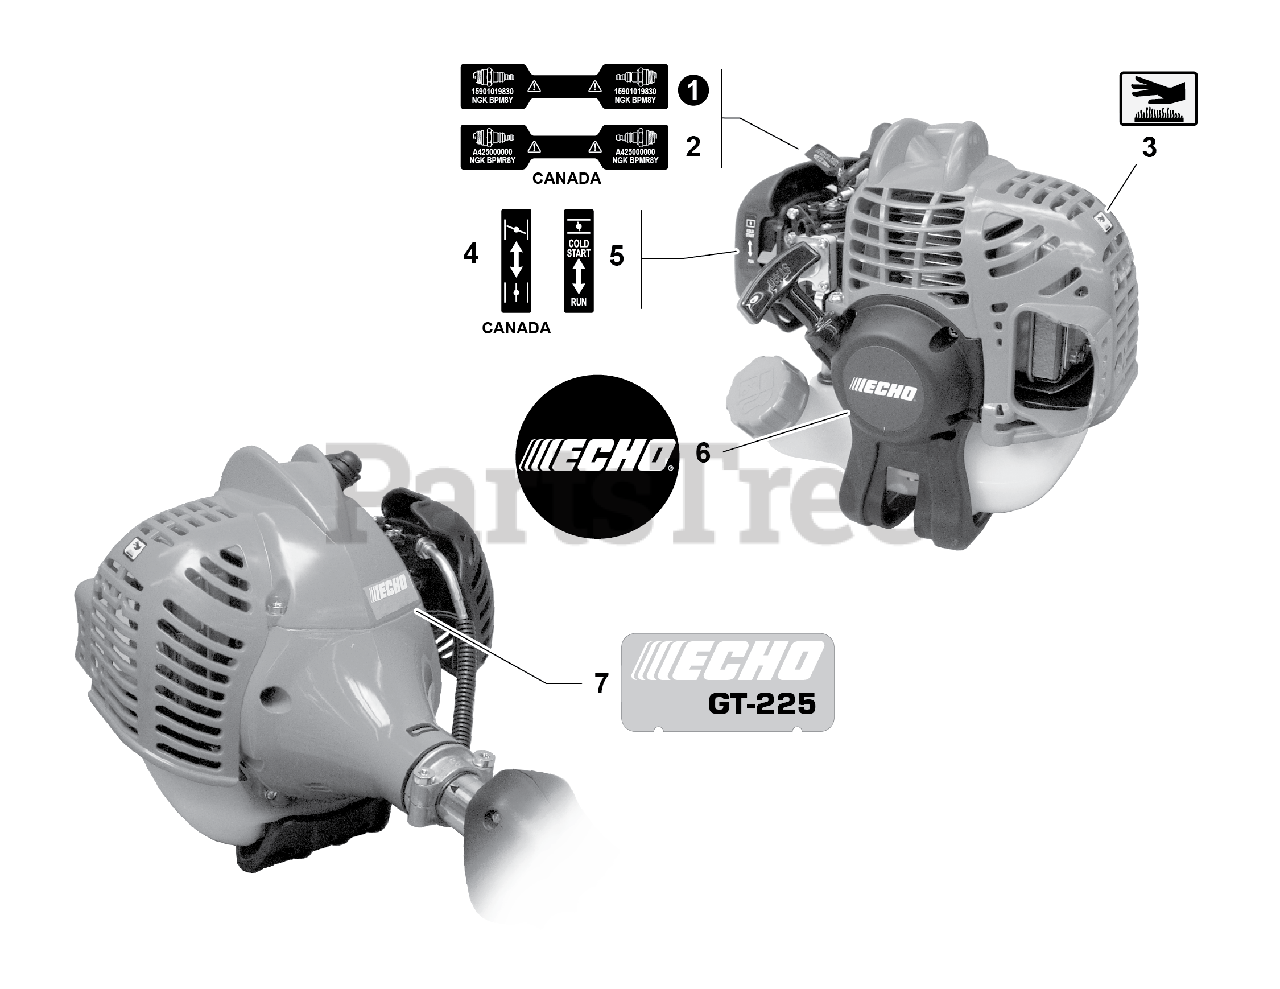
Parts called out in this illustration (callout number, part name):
1	LABEL, SPARK PLUG - BPM8Y
2	LABEL, SPARK PLUG - BPMR8Y
3	LABEL, CAUTION - HOT
4	LABEL, CHOKE
5	LABEL, CHOKE
6	LABEL, ECHO
7	LABEL, MODEL
